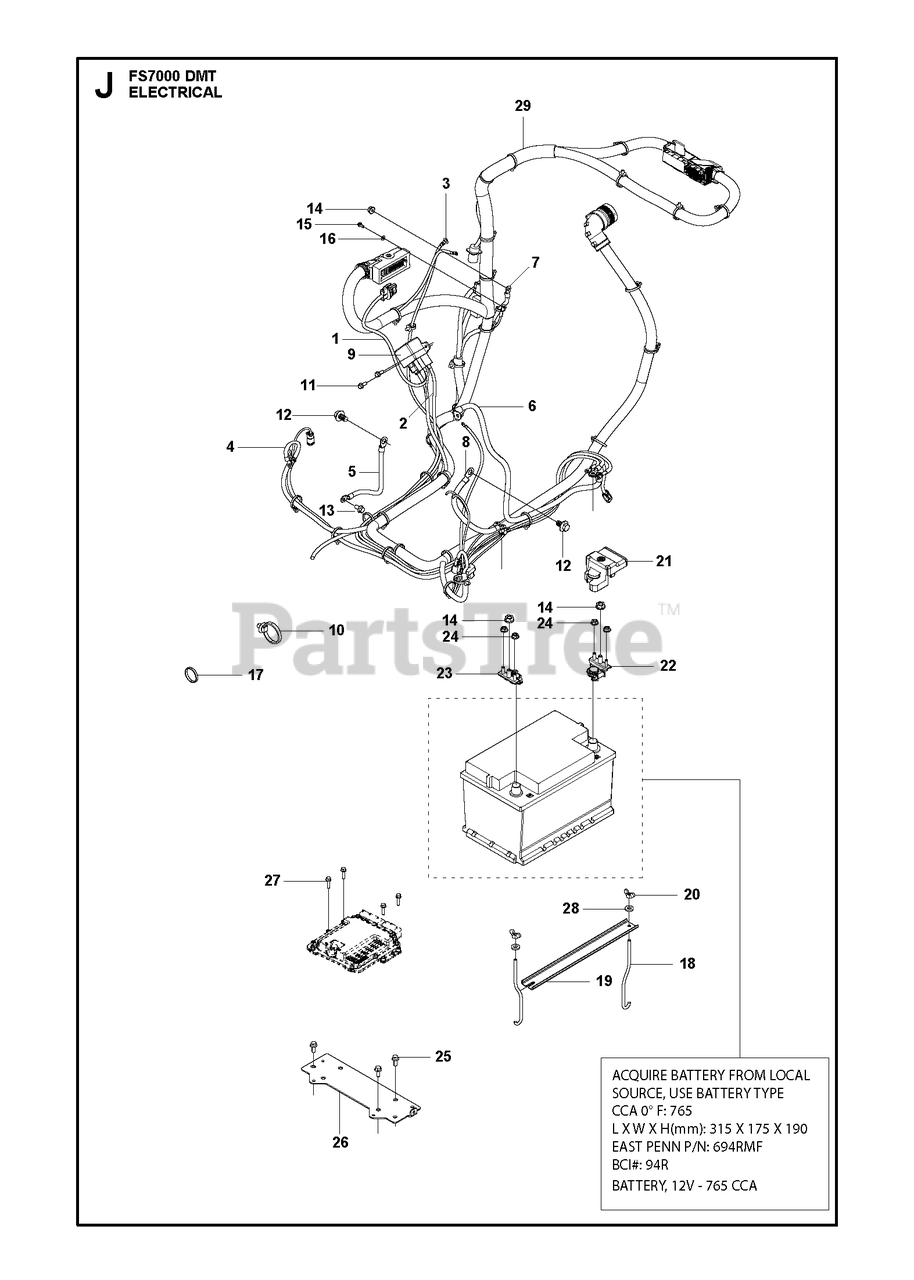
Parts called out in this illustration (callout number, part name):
14	HEXAGON NUT FLANGE
15	SCREW EHHM
16	WASHER
24	HEXAGON NUT FLANGE
